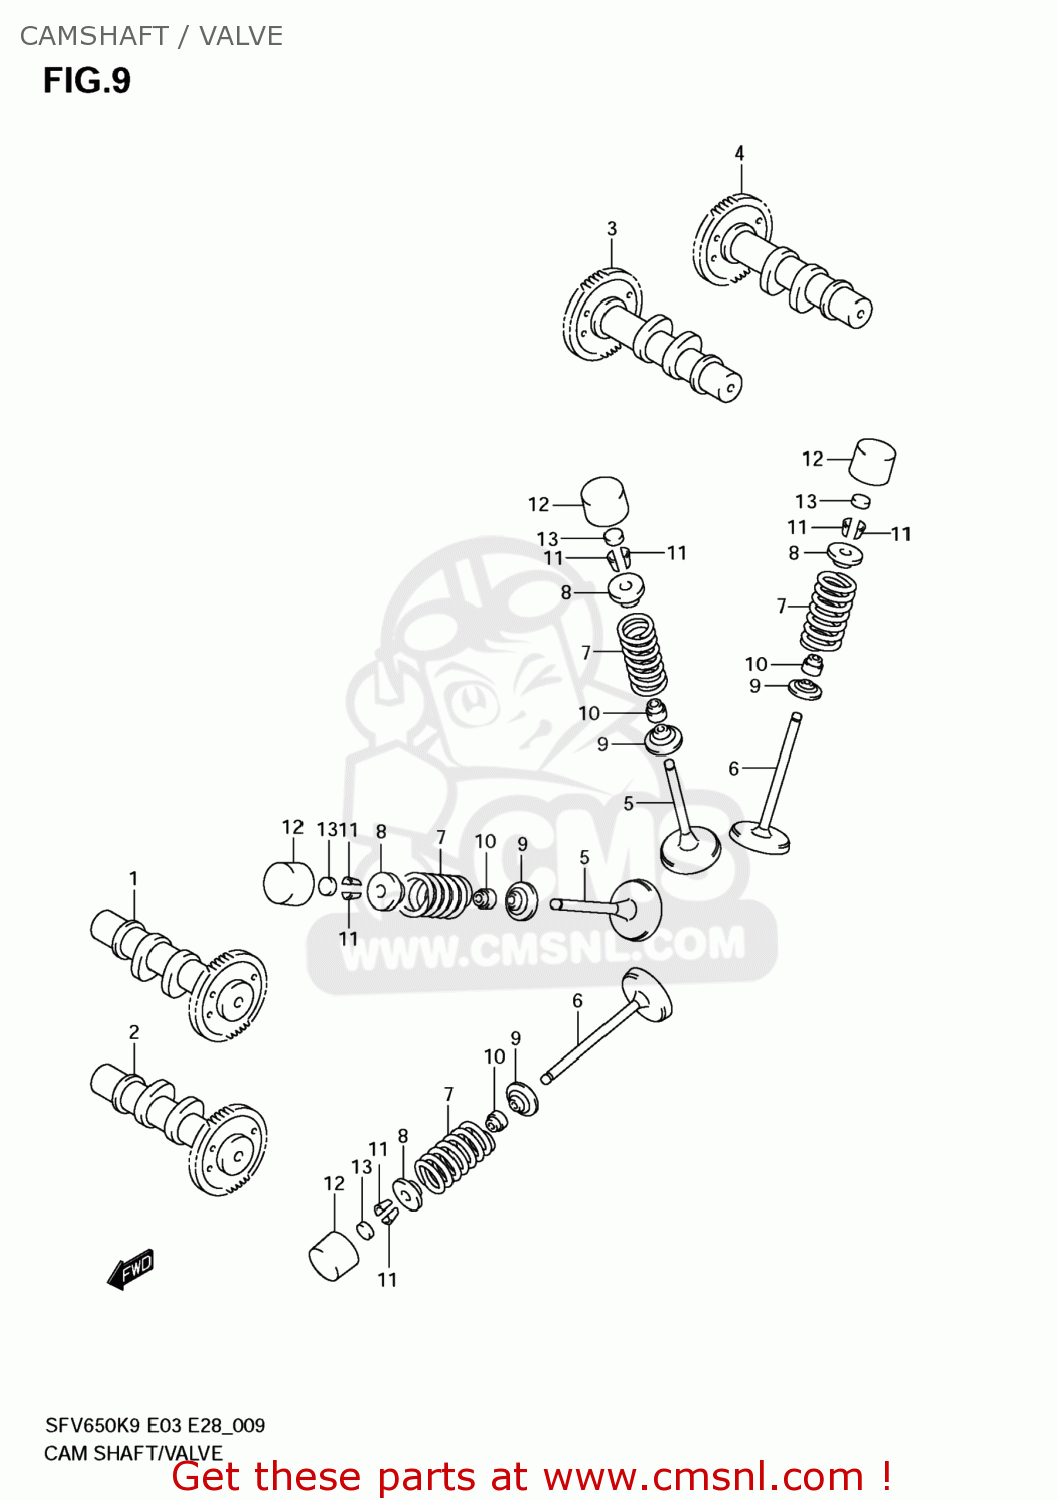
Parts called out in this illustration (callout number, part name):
1	CAMSHAFT,INTAKE FR
2	CAMSHAFT,EXHAUST FR
3	CAMSHAFT,INTAKE RR
4	CAMSHAFT,EXHAUST RR
5	VALVE,INTAKE
6	VALVE,EXHAUST
7	SPRING,VALVE
8	RETAINER,VALVE SPRING
9	SEAT,VALVE SPRING
10	SEAL,OIL(4.5X10X8)
11	COTTER VALVE
12	TAPPET
13	SHIM,TAPPET
14	SHIM SET,TAPPET
15	CASE,TAPPET SHIM
